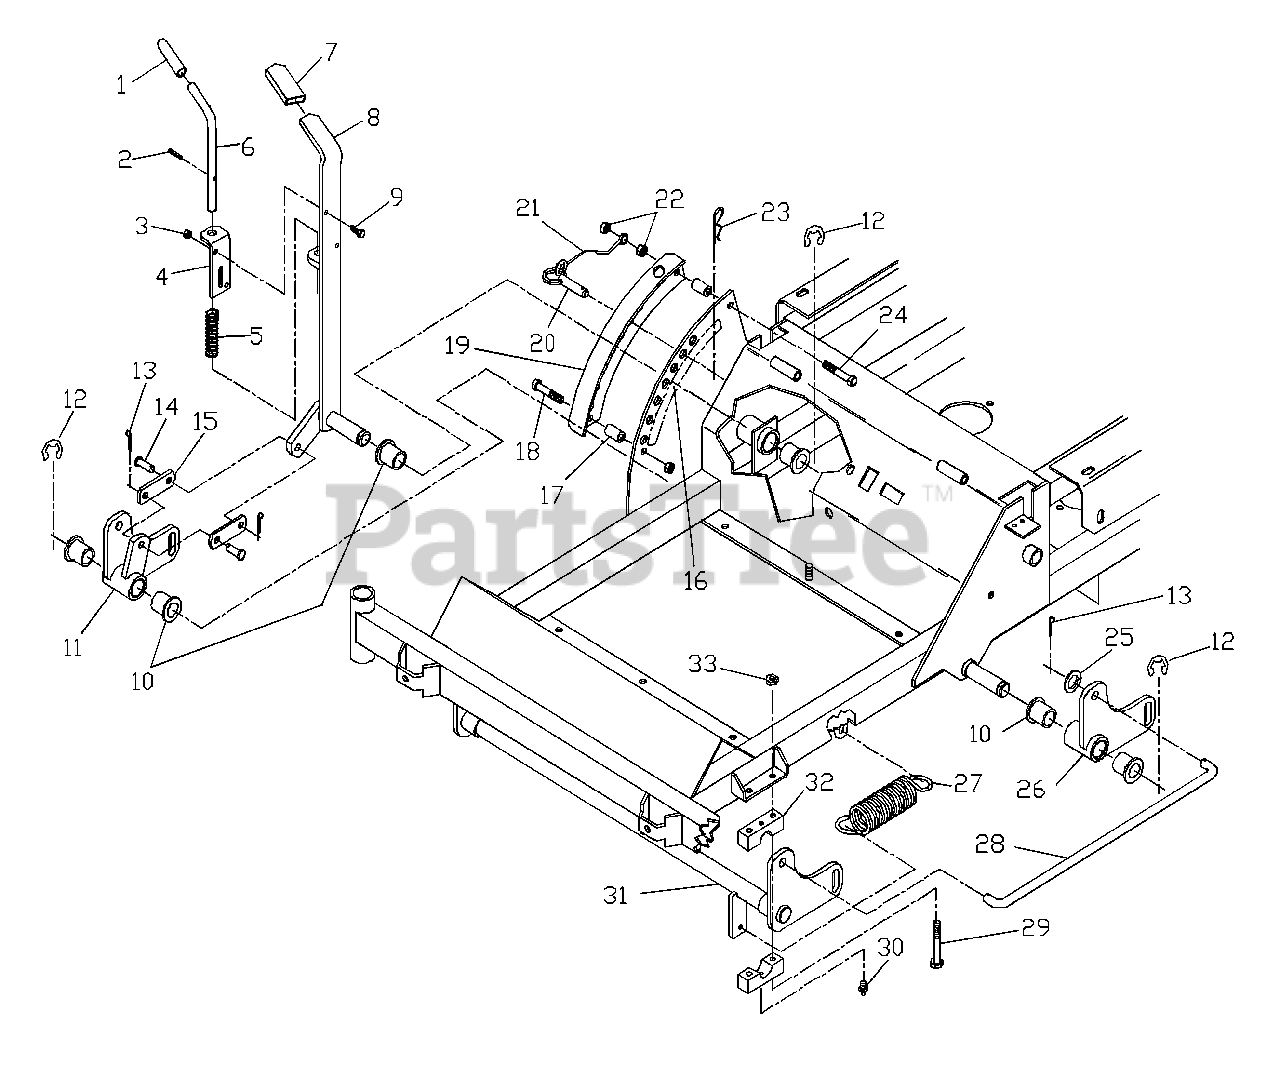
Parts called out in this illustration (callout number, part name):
2	3/16 X 1 ROLL PIN
3	NUT 1/4C CENTER LOCK
4	PIN MT, UPPER
8	LEVER WLDMT
9	1/4C X 3/4 HCS
10	FLANGED BUSHING
11	BELLCRANK WLDMT - RT
12	7/8 'E' RING
13	1/8 X 3/4 COTTER PIN
14	3/8 X 1 1/8 CLEVIS PIN
16	DECAL, LOCATOR
18	HCS 3/8C X 2
19	LOCATOR WLDMT
22	NUT 3/8C CENTERLOCK
23	#4 HAIRPIN
24	HCS 3/8C X 2 1/4
25	1/2 MACH. BUSHING
26	BELLCRANK WLDMT - LT
29	HCS 5/16C X 2 1/2
31	LIFT WLDMT
32	LIFT BLOCK
33	NUT 5/16C CENTERLOCK
